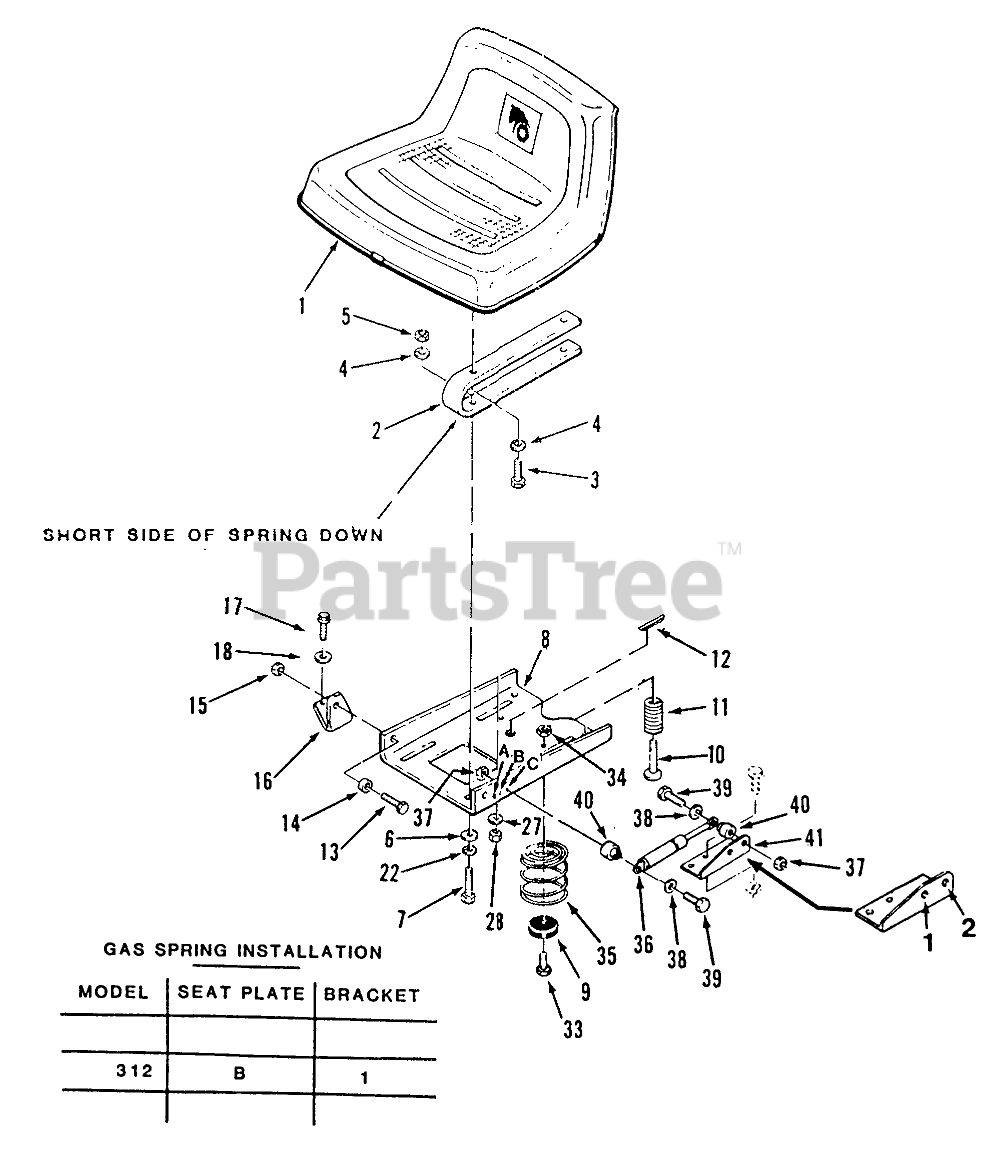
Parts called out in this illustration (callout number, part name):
2	Seat Spring
3	Bolt
4	Lockwasher
5	Nut
6	WASHER 5/16 SAE
7	HHCS
8	PLATE-SEAT PIVOT B
9	BUMPER
11	SPRING-SEAT SWITCH
12	Cotter Pin
13	HHCS
14	BUSHING
15	Nut
16	Bracket-Pivot RH
17	Bolt
18	WASHER 5/16 SAE
30	RIVET
33	Bolt
34	Nut
35	SPRING
36	GAS SPRING
37	Nut
39	Bolt
40	SPACER
41	BRACKET-CYLINDER R
